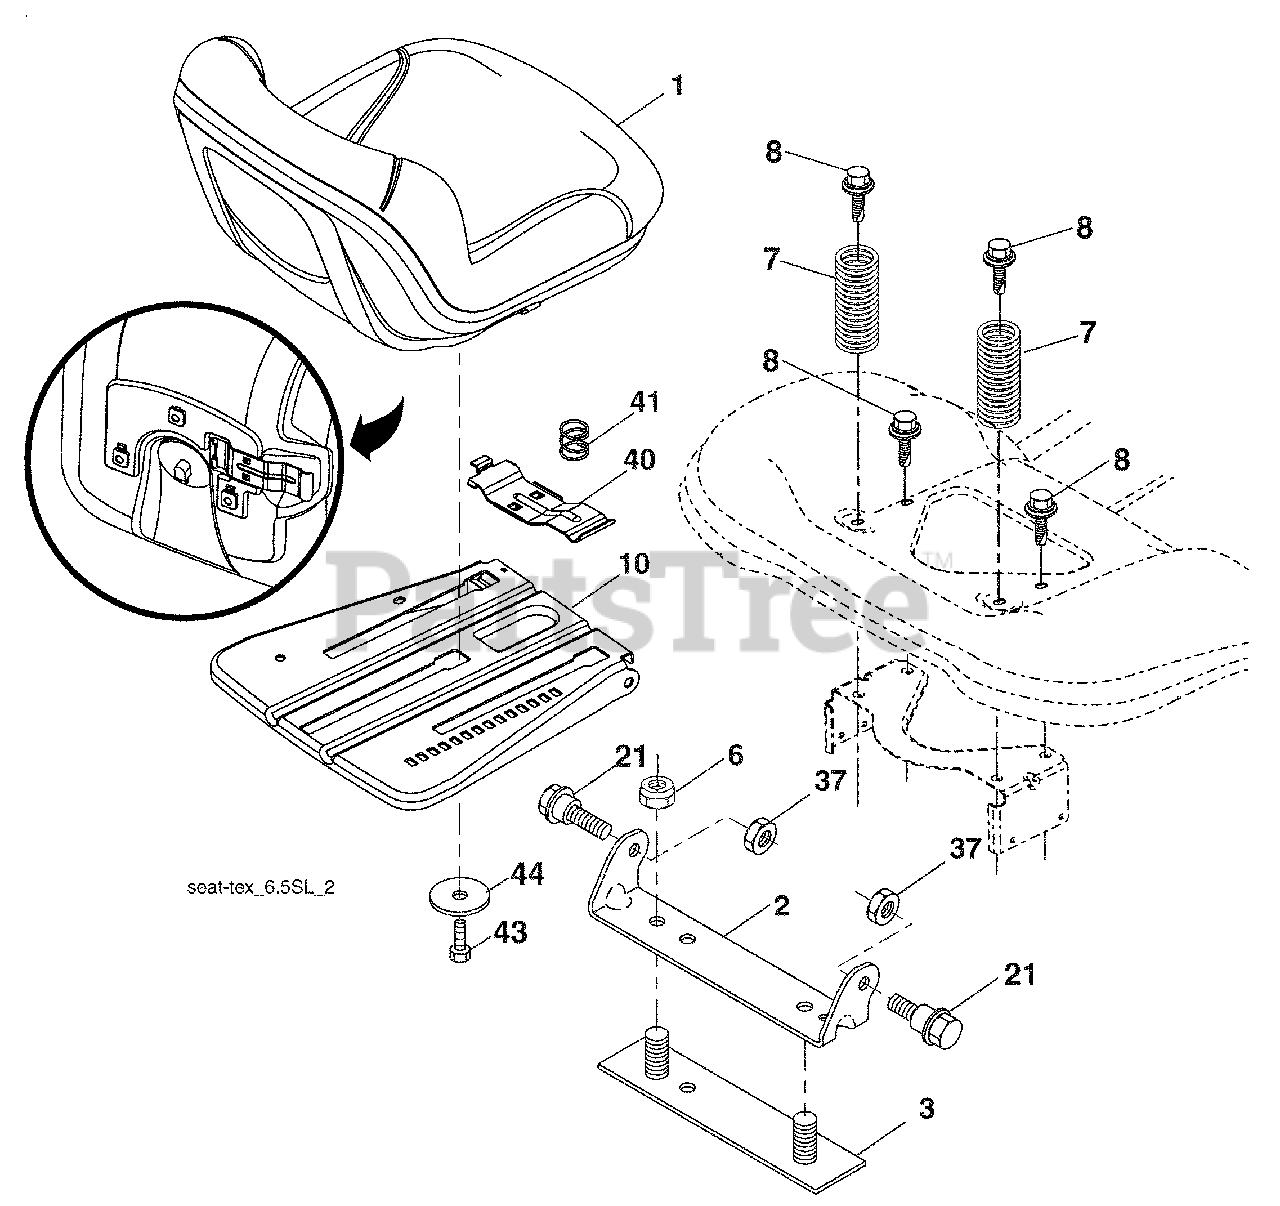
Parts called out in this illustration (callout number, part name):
1	Seat
2	Bracket Pivot Fender
3	Strap, Asm Fender
6	Nut, Lock w/Ins. 3/8-16 unc
7	Spring, Seat Cprsn
8	Bolt 5/16-18 unc x 3/4 w/Sems
10	Pan, Seat
21	Bolt, Shoulder 5/16-18
37	873 80 05-00 Nut, Lock 5/16-18 unc
40	532 19 76-61 Handle Slide Seat
41	532 19 82-00 Spring Latch Seat
43	874 76 06-12 Bolt 3/8-16 x 3/4
44	819 13 38-12 Washer 13/32 x 2-3/8 x 12 Ga.
